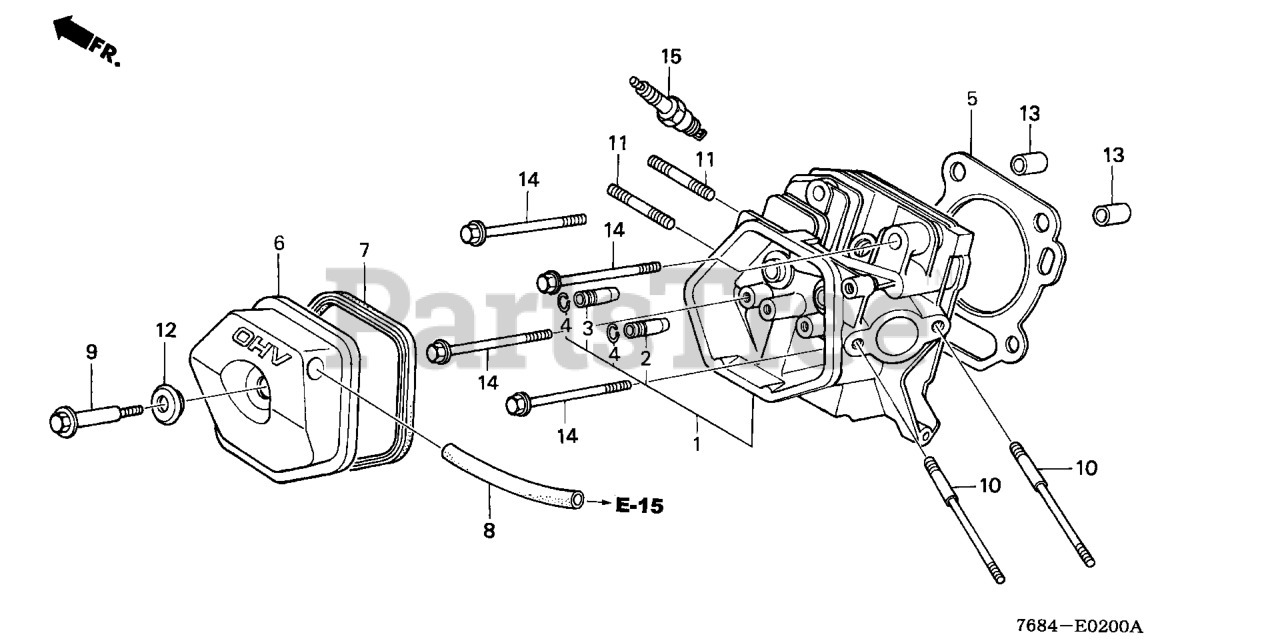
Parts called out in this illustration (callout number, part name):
1	CYLINDER HEAD
2	GUIDE, VALVE (OS)
4	CLIP, VALVE GUIDE
5	GASKET, CYLINDER HEAD
6	COVER, HEAD
7	GASKET, CYLINDER HEAD COVER
8	TUBE, BREATHER
9	BOLT, HEAD COVER
10	BOLT, STUD (8X123)
11	BOLT, STUD
12	WASHER, HEAD COVER
13	PIN A, DOWEL (12X20)
14	BOLT, FLANGE (10X80)
15	SPARK PLUG (BPR5ES) (NGK)
15	SPARK PLUG (W16EPR-U) (DENSO)
